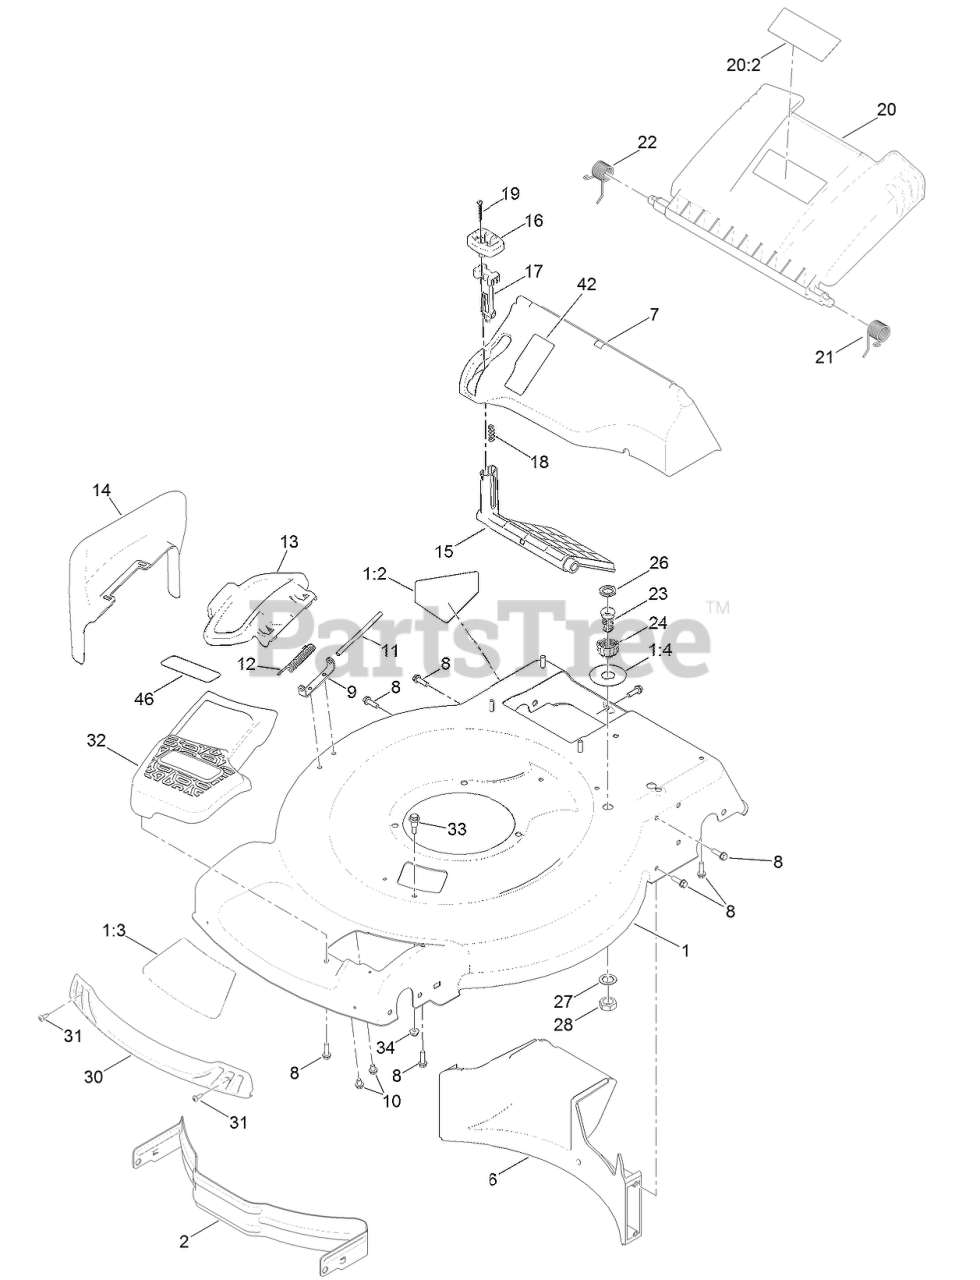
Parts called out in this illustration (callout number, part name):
1	HOUSING ASM
1:2	DECAL-DANGER
1:3	DECAL-DECK
1:4	DECAL-PORT, WASHOUT
2	BAFFLE-FRONT
6	BAFFLE-REAR
7	CHUTE-RECYCLE
8	SCREW-HWH
9	BRACKET-COVER
10	SCREW-HWH
11	ROD-COVER
12	SPRING-TORSION
13	DEFLECTOR-SIDE
14	CHUTE-DISCHARGE, SIDE
15	DEFLECTOR-RECYCLE
16	KNOB-RECYCLE
17	LATCH-RECYCLE
18	SPRING-COMPRESSION
19	SCREW-PPH
20	REAR DOOR ASM
20:2	DECAL-WARNING
21	SPRING-TORSION
22	SPRING-TORSION
23	PORT-WASHOUT
24	COUPLING-HOSE, WASHOUT PORT
26	WASHER-SEAL, WASHOUT PORT
27	WASHER-TOOTH, INTERNAL
28	NUT-JAM
30	BUMPER
31	SCREW-FORMING, THREAD
32	COVER-BELT, FRONT
33	BOLT-SHOULDER
34	NUT-LOCK, NI
46	DECAL-COVER
